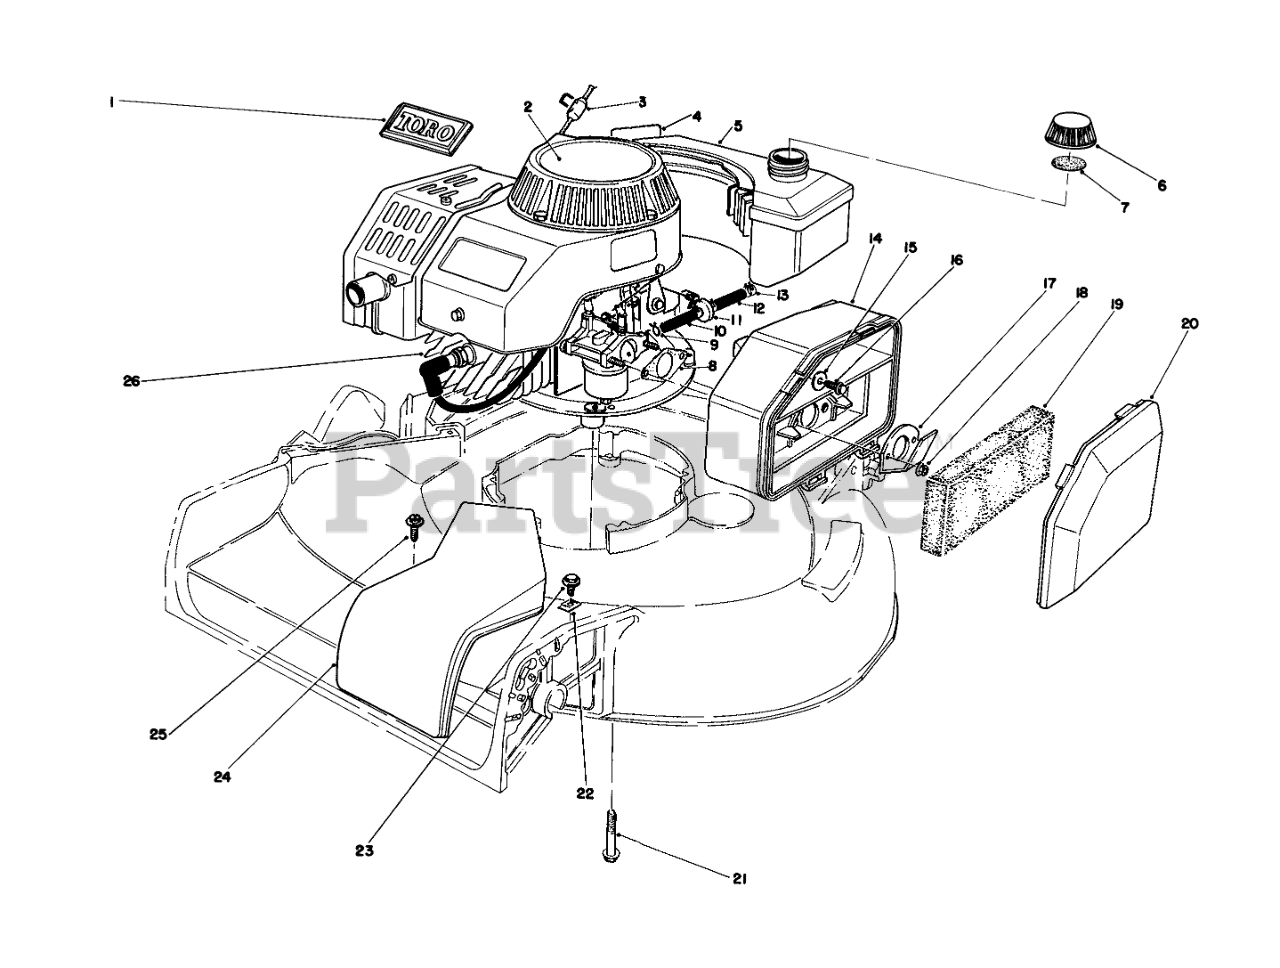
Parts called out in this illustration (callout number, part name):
1	TORO LOGO PLT
2	DECAL- 2 CYC RECOIL
3	STOP-ROPE
4	Decal-Maintenance
5	Fuel Tank Assembly
6	Gas Cap Assembly (Incl. Ref. #7)
7	GAS CAP GASKET
8	GASKET-AIR CLEANER
9	CLAMP-HOSE
10	HOSE-FUEL
11	FILTER-FUEL
12	HOSE-FUEL
13	CLAMP-FUEL LINE
14	AIR CLEANER
15	WASHER-FLAT
16	SCREW-HH
17	SPIT BACK DEFLECTOR
18	NUT-LOCK
19	FILTER
20	AIR CLEANER COVER
21	FLG SCREW,3/8-16X2.000
22	Cable Clamp
23	SCREW-HWHTF
24	Cow-Belt
25	SCREW
26	Engine
